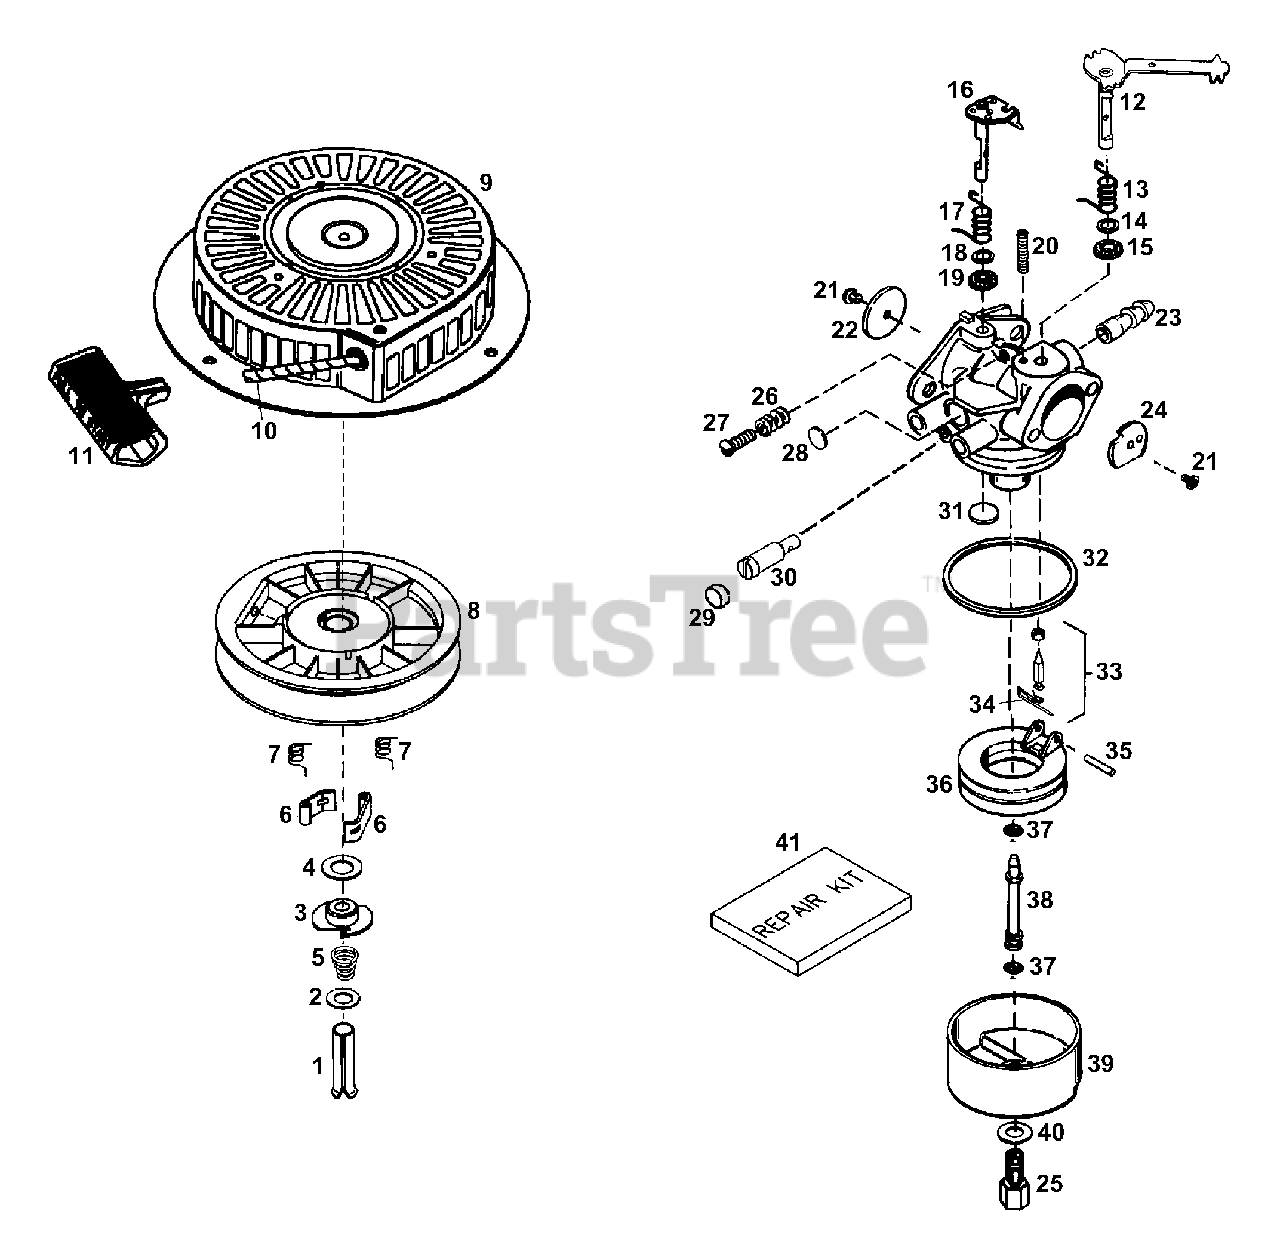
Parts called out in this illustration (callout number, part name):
1	Spring Pin
5	Brake Spring
6	Starter Dog
7	Dog Spring
8	Pulley & Rewind Spring Assembly
9	Starter Housing Assembly
10	Starter Rope (Length 98" x 9/64" dia.)
11	Starter Handle
12	Choke Shaft & Lever Assembly
13	Choke Return Spring
14	Dust Seal Washer
15	Dust Seal (Choke)
16	Throttle Shaft & Lever Assembly
17	Throttle Return Spring
18	Dust Seal Washer
19	Dust Seal (Throttle)
20	Choke Positioning Spring
21	Shutter Screw
22	Throttle Shutter
23	Fuel Fitting
24	Choke Shutter
25	High Speed Bowl Nut
26	Tension Spring
27	Throttle Crack Screw/Idle Speed Screw
28	Welch Plug, Idle Mixture Well
29	Idle Restrictor Screw Cap
30	Idle Restrictor Screw
31	Welch Plug, Atmospheric Vent
32	Float Bowl O-Ring
33	Inlet Needle, Seat & Clip
34	Spring Clip
35	Float Shaft
36	Float
37	O-Ring, Main Nozzle Tube
38	Main Nozzle Tube
39	Float Bowl
40	Bowl Nut Washer
41	Repair kit
